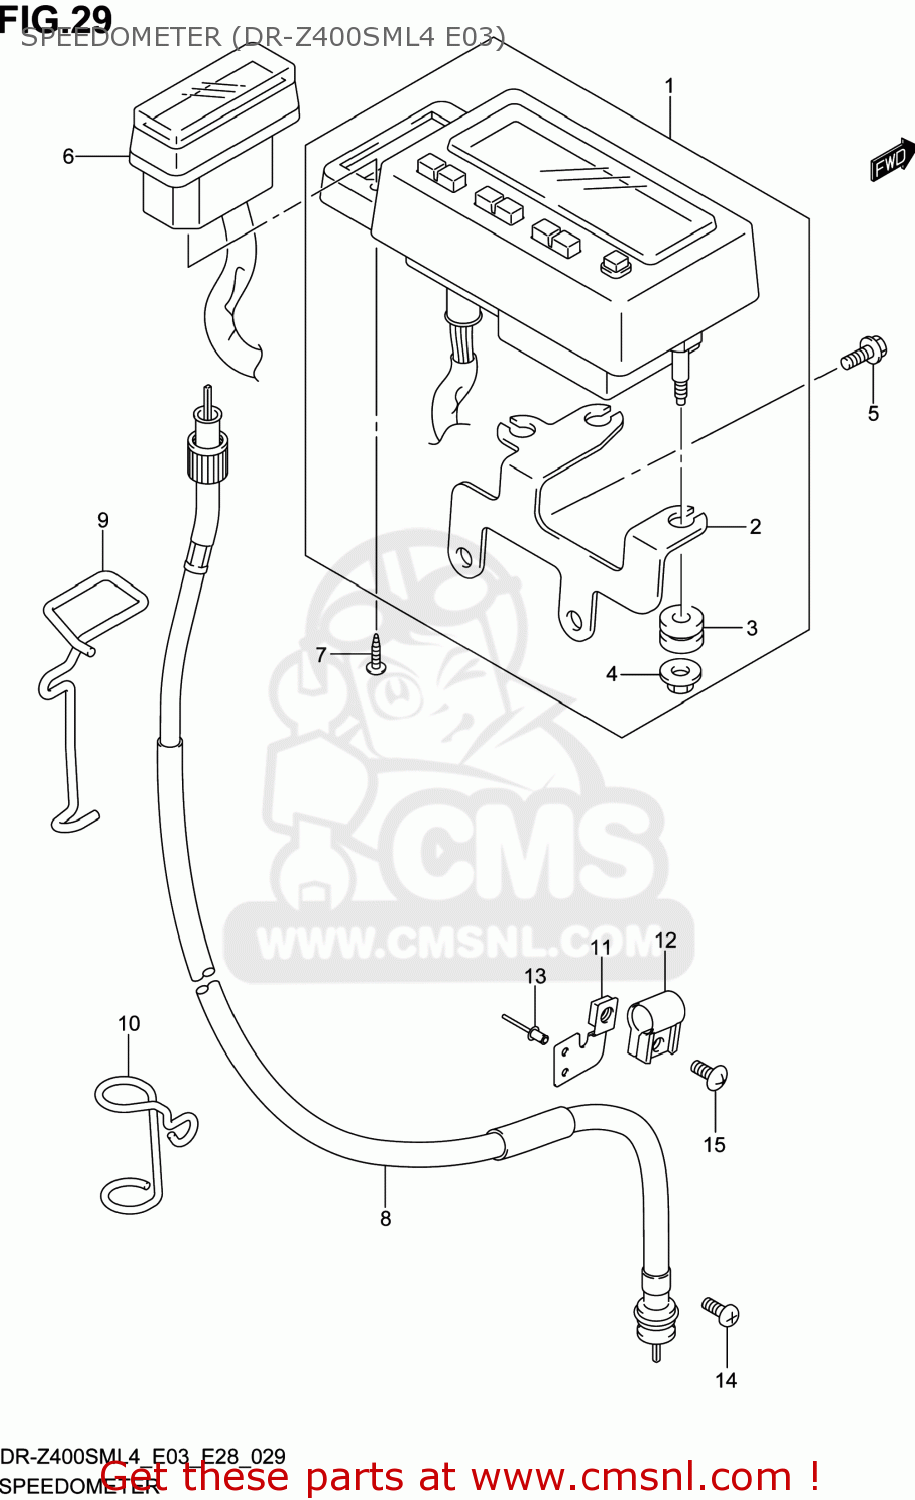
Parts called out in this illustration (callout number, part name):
1	SPEEDOMETER ASSY
2	BRACKET
3	CUSHION,METER
4	NUT
5	BOLT
6	BOX ASSY,PILOT LAMP
7	SCREW
8	CABLE ASSY,SPEEDOMETER
9	GUIDE,SPEEDOMETER CABLE NO.3
10	GUIDE,METER CABLE NO.1
11	GUIDE,METER CABLE NO.2
12	CLAMP,BRAKE HOSE
13	RIVET
14	SCREW
15	SCREW
